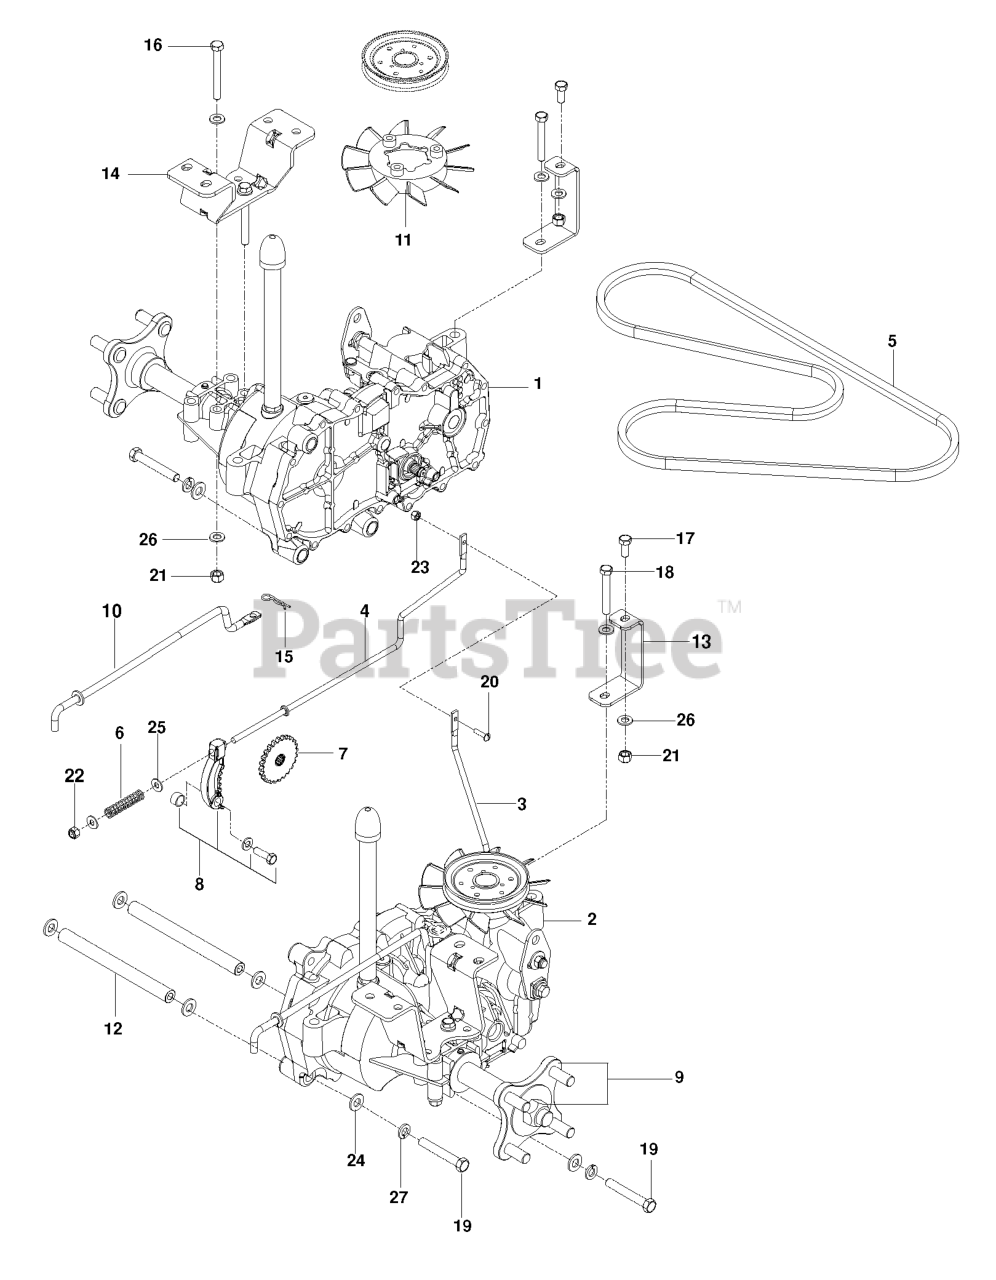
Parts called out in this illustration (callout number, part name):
1	HG_EZT, LT
2	HG_EZT, RT
3	LINKAGE.BRAKE.LT
4	LINKAGE, BRAKE RT
5	BELT, HYDRO PUMP
6	SPRING
7	HG_DISC COG BRAKE
8	HG_KIT BRAKE ARM (EZT)
9	HG_KIT, HYDRO-GEAR HUB
10	LINKAGE, BYPASS, EZT
11	HG_HYDRO FAN
12	SPACER TUBE, EZT
13	Front Trans Support, Pntx 431
14	BRACKET.EZT.MOUNT.REAR.PNTX431
15	HAIRPIN #2
16	BOLT HEX**
17	BOLT
19	Screw, Hex Head.38-16 X 2.5
20	SCR #10-24 X 3/4
21	NUT.71038.31-18.HEX.NYLOCK
22	LOCKNUT
23	NUT 10-24 NYLOC
25	WASHER
26	WASHER
27	LOCKWASHER
